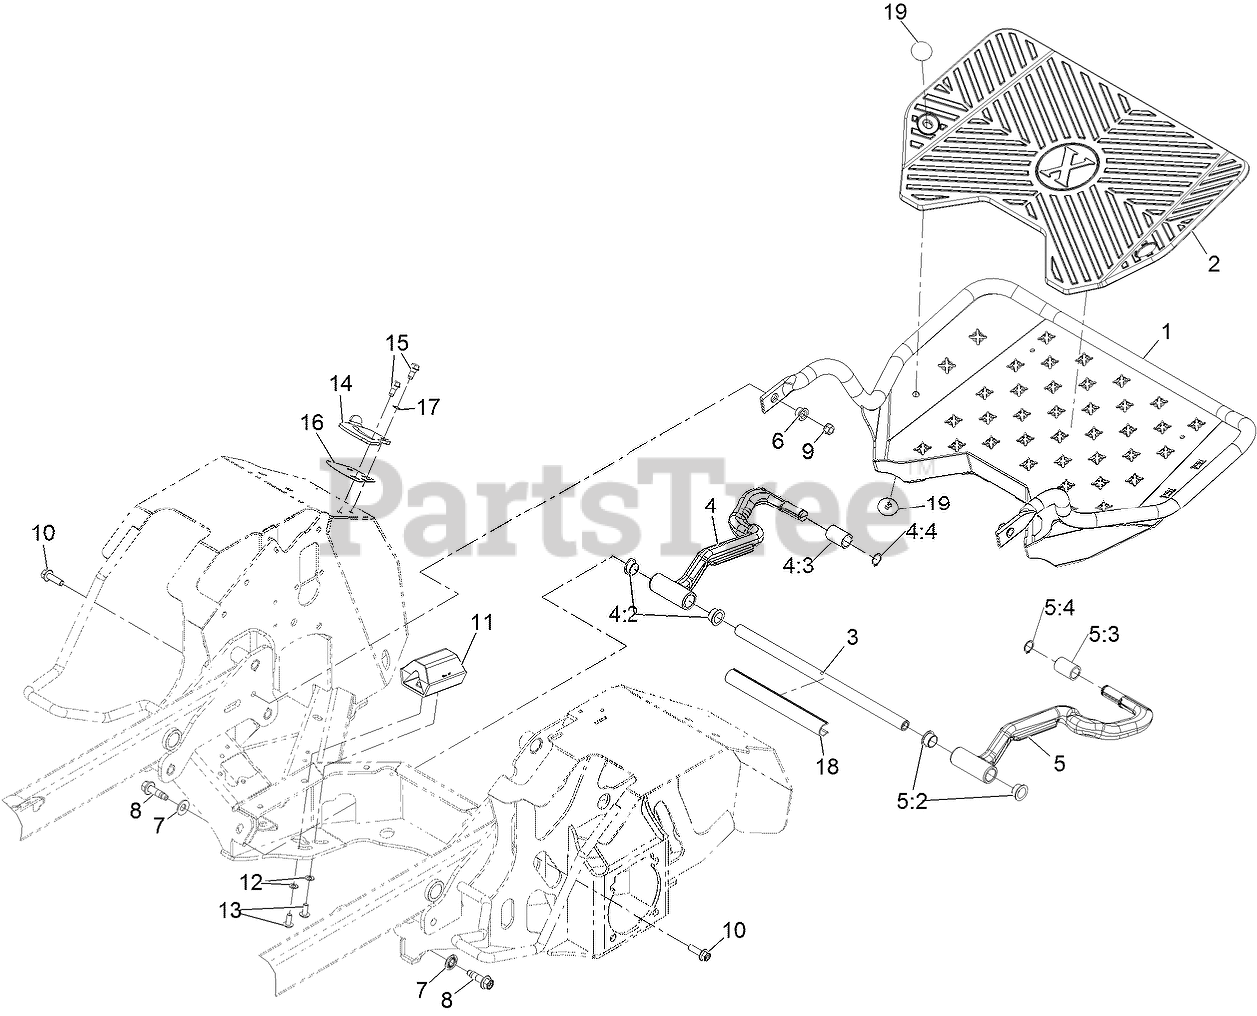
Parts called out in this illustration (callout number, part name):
1	Weld, Platform
2	Mat, Platform
3	SHAFT, CROSS
4	ASM, Rt Arm W/ Bushings
4:2	BUSHING-FLANGE
4:3	Bushing, Sleeve
4:4	RING-SNAP
5	ASM, Lt Arm W/ Bushings
5:2	BUSHING-FLANGE
5:3	Bushing, Sleeve
5:4	RING-SNAP
6	BUSHING-FLANGED
7	WASHER-SPRING
8	Screw-HHF
10	SCREW, HHF
12	WASHER-LOCK
13	SCREW-TORX
14	Latch, Platform
15	SCREW-SHOULDER
16	Decal-Latch Lock
17	Washer, Wave
19	Rivet-Ratchet
